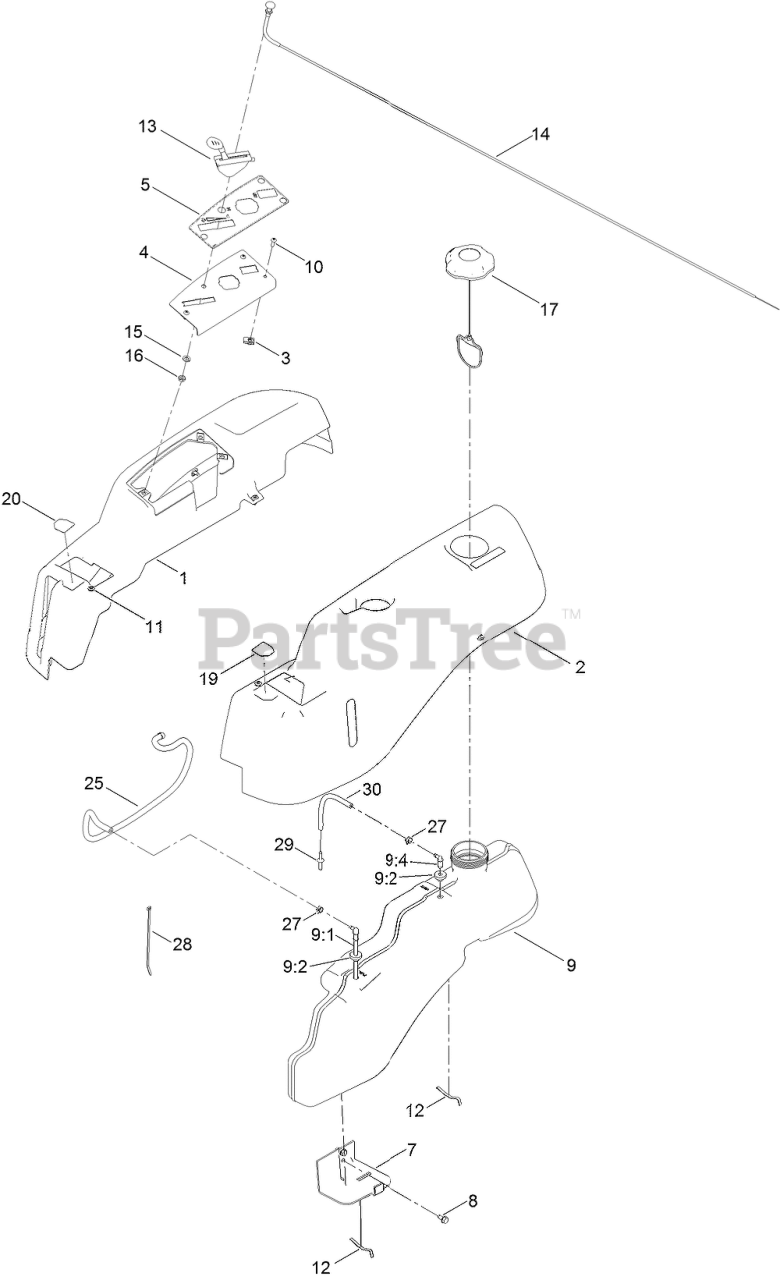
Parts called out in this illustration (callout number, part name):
1	POD-RH, NARROW
2	POD-LH, NARROW
4	PLATE-CONTROL
5	DECAL-PANEL, CONTROL
7	SUPPORT-TANK, FRONT
8	SCREW-HWHTF
9	FUEL TANK ASM
9:1	CONNECTOR-ELBOW, 90 DEG
9:2	BUSHING
9:4	FITTING-PLASTIC
10	SCREW-PRH
11	SCREW-SHOULDER
12	SPRING
13	CABLE-THROTTLE
14	CABLE-CHOKE
15	WASHER-LOCK
16	NUT-HJ
17	CAP-FUEL, RATCHETING
19	DECAL-LEVER, CONTROL (LH)
20	DECAL-LEVER, CONTROL (RH)
25	HOSE-FUEL
27	CLAMP-HOSE
28	TIE-CABLE
29	ADAPTOR-ORIFICE
30	HOSE-FUEL
